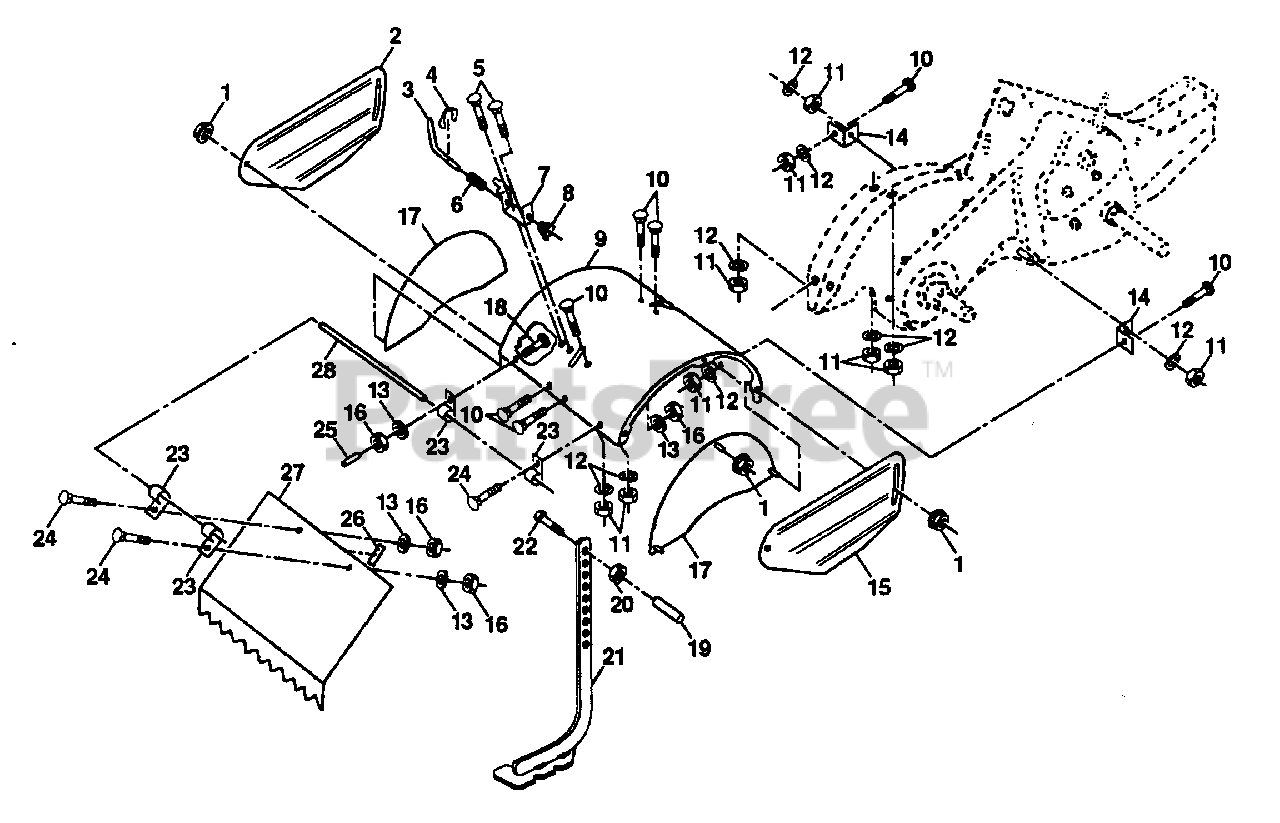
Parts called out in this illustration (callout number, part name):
1	Nut, Flange 5/16-18
2	Shield, Side, Outer, L.H.
3	Pin, Depth Stake
5	Bolt, Carriage 5/16-18 x 1
7	Bracket, Latch
8	Spring, Depth Stake
10	Bolt, Carriage 5/16-18 x 3/4 Gr. 5
11	Nut, Hex 5/16-18
12	Washer, Lock 5/16
13	Washer, Lock 1/4
14	Bracket, Shield Tine
15	Shield, Side, Outer R.H.
16	Nut, Fin, Hex, 1/4-20
18	Bolt, Carriage 1/4-20 x 1-1/4 Gr. 5
20	Nut, Hex 3/8-16
21	Stake, Depth
22	Bolt, Hex 3/8-16 x 2
24	Bolt, Carriage 1/4-20 x 1/2 Gr. 5
25	Cap, Vinyl
27	Shield, Leveling
